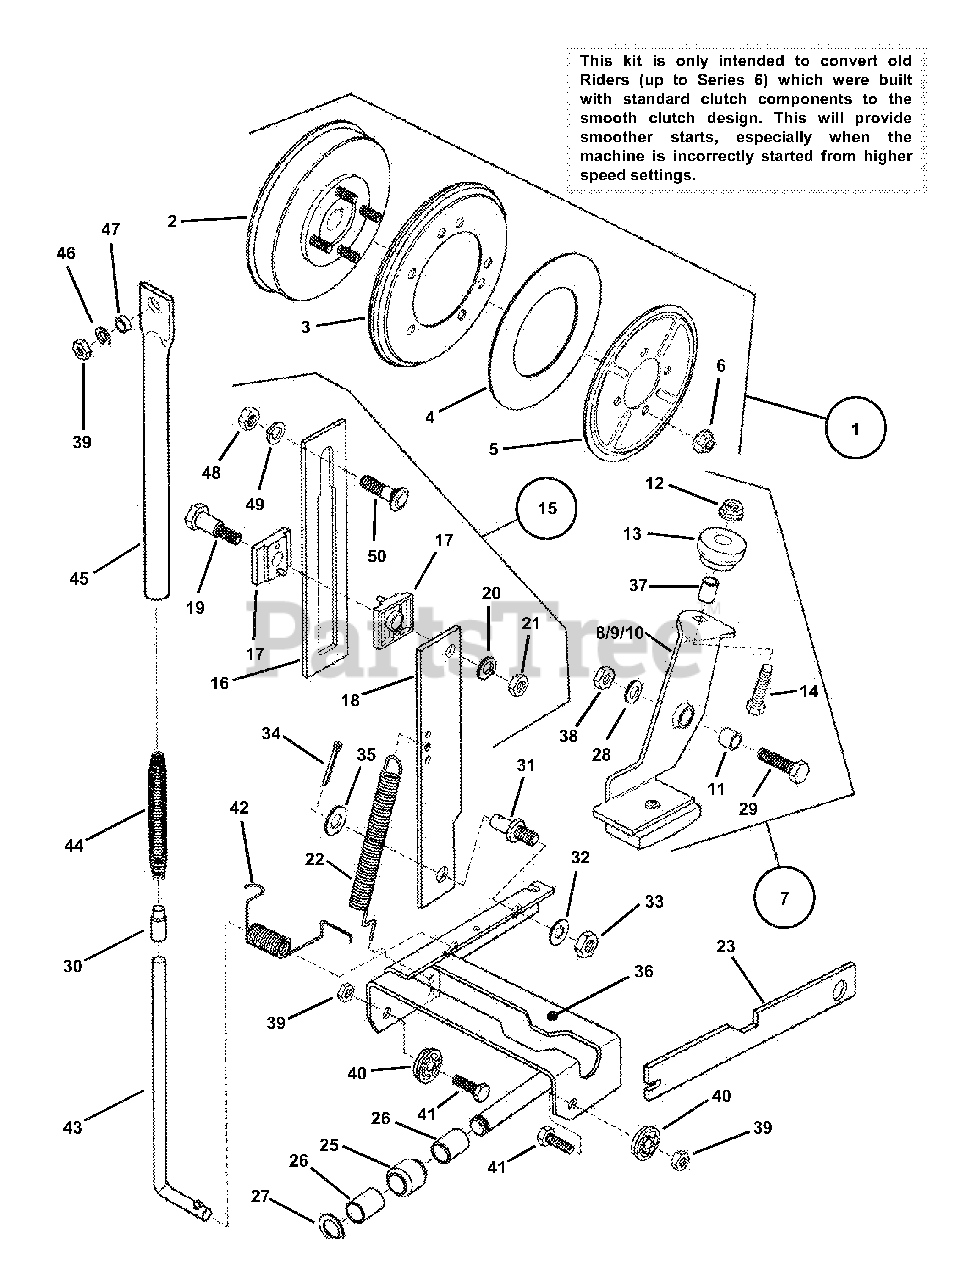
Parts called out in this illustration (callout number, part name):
1	ASSEMBLY, Smooth Clutch
2	ASSEMBLY, Driven Disc Hub
3	FRICTION RING
4	WASHER, Thrust
5	PLATE
6	NUT, 5/16-18 Hex Flange Lock
7	ASSEMBLY, Brake Lever
8	LINING, Brake
9	RIVET, 3/16 x .344
10	LEVER, Brake
11	SPACER
12	NUT, 1/4-20 Hex Flange
13	ROLLER
14	SCREW, 1/4-20 x 3/4" Hex Head Cap
15	ASSEMBLY, Guide & Link
16	GUIDE, Clutch Link
17	SLIDE HALF
18	LINK, Clutch
19	BOLT, 5/16-18 Shoulder
20	WASHER, 5/16" Split Lock
21	NUT, 5/16-18 Hex
22	SPRING, Clutch/Brake
23	TOOL, Smooth Clutch
25	ROLLER, Parking Brake
26	SPACER, Roller
27	RING, 1/2" External Retaining
28	WASHER, 1/4 Flat
29	SCREW, 1/4-28 x 1" Hex Head Cap
30	SPACER, Spring (Plug)
31	STUD, Clutch Link (3/8-24 thread)
32	WASHER, 3/8" Internal Tooth Lock
33	NUT, 3/8"-24 Hex
34	PIN, 3/32 x 1" Cotter
35	WASHER, 3/8" Flat
36	LIFT, Yoke
37	BUSHING
38	NUT, 1/4-28 Hex Top Lock
39	NUT, 5/16-24 Hex Center lock
40	BEARING, Yoke
41	SCREW, 5/16-24 x 3/4" Hex Head Cap
42	SPRING
43	ROD
44	SPRING, 25 Coils
45	TUBE
46	WASHER, 5/16 Split Lock
47	ROLLER
48	NUT, 3/8-16 Hex
49	WASHER, 3/8" Split Lock
50	BOLT, 3/8-16 x 3/4" Short Neck Carriage
